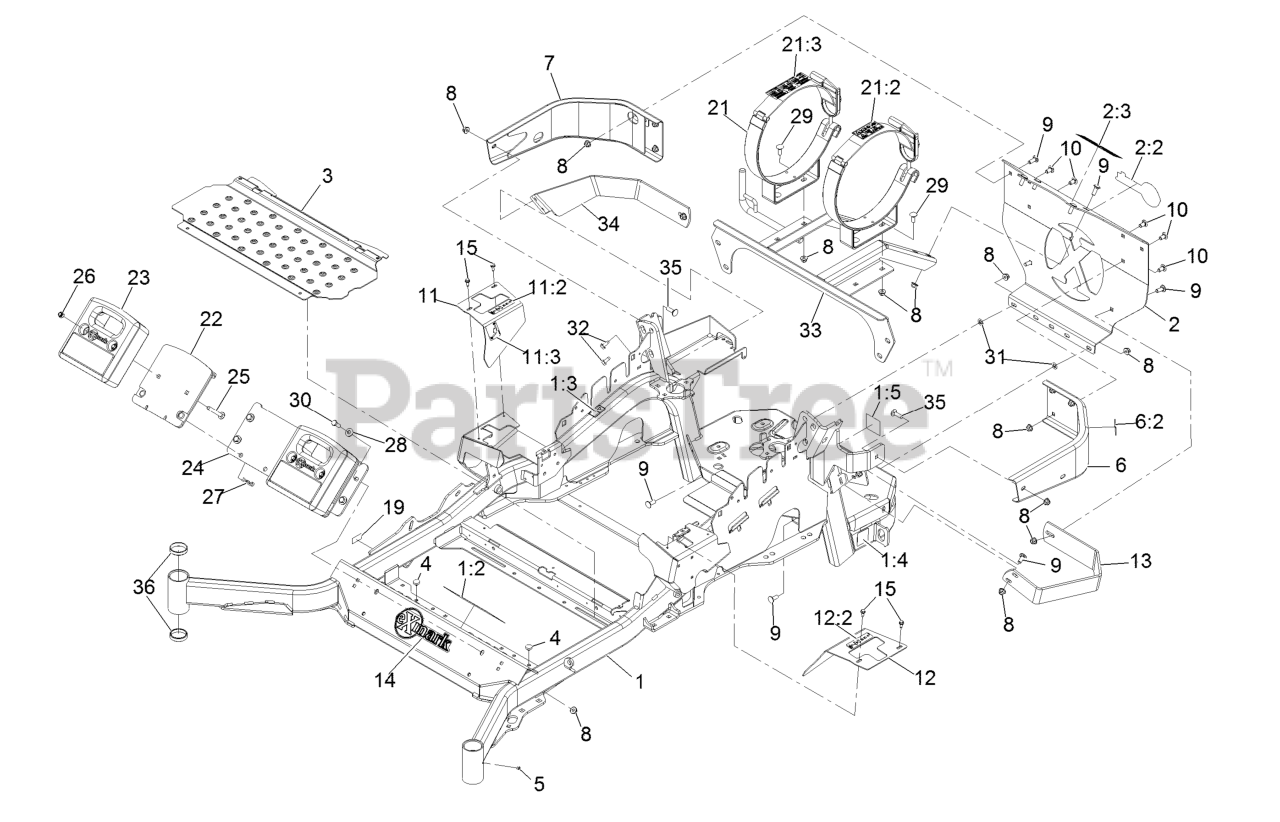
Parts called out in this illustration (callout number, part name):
1	MAINFRAME ASM
1:2	DECAL-WARNING
1:3	DECAL-DANGER
1:4	DECAL-HAZARD, PINCHED FINGER
1:5	DECAL-SPARK ARRESTER
2	REAR GUARD-LP W/DECALS
2:2	DECAL-EXMARK LOGO
2:3	Decal-LPG Fuel Tank Replacement
6	LH BUMPER ASM
6:2	DECAL-WARNING
7	BUMPER-RH
8	NUT-HF, NI
9	SCREW-CARR
10	SCREW-CARR
11	RH MOTION CONTROL COVER ASM
11:2	DECAL-CONTROL, MOTION
11:3	DECAL-PARK BRAKE, CE
12	LH MOTION CONTROL COVER ASM
12:2	DECAL-CONTROL, MOTION
13	GUARD-MUFFLER
14	DECAL-EXMARK LOGO
15	SCREW-HWH
19	Decal-Patent
21	TANK BRACKET ASM (SET)
21:2	Decal-LPG Warning
21:3	Decal-LPG Tank Spec
22	WLD,WEIGHT MOUNT
23	WEIGHT,CAST 36LB
24	PLATE,WEIGHT ASM MOUNT
25	SCREW-CARR
26	NUT-LOCK, NI
27	PIN-HAIR
28	WASHER-BELLEVILLE
29	BOLT-CARR
30	SCREW-HH
31	NUT-PUSH
32	Screw-HWH 5/16-18 X 3/4 Tf
33	SUPPORT-TANK
34	STRAP-GUARD
35	BOLT-CARR
36	CUP-BEARING
